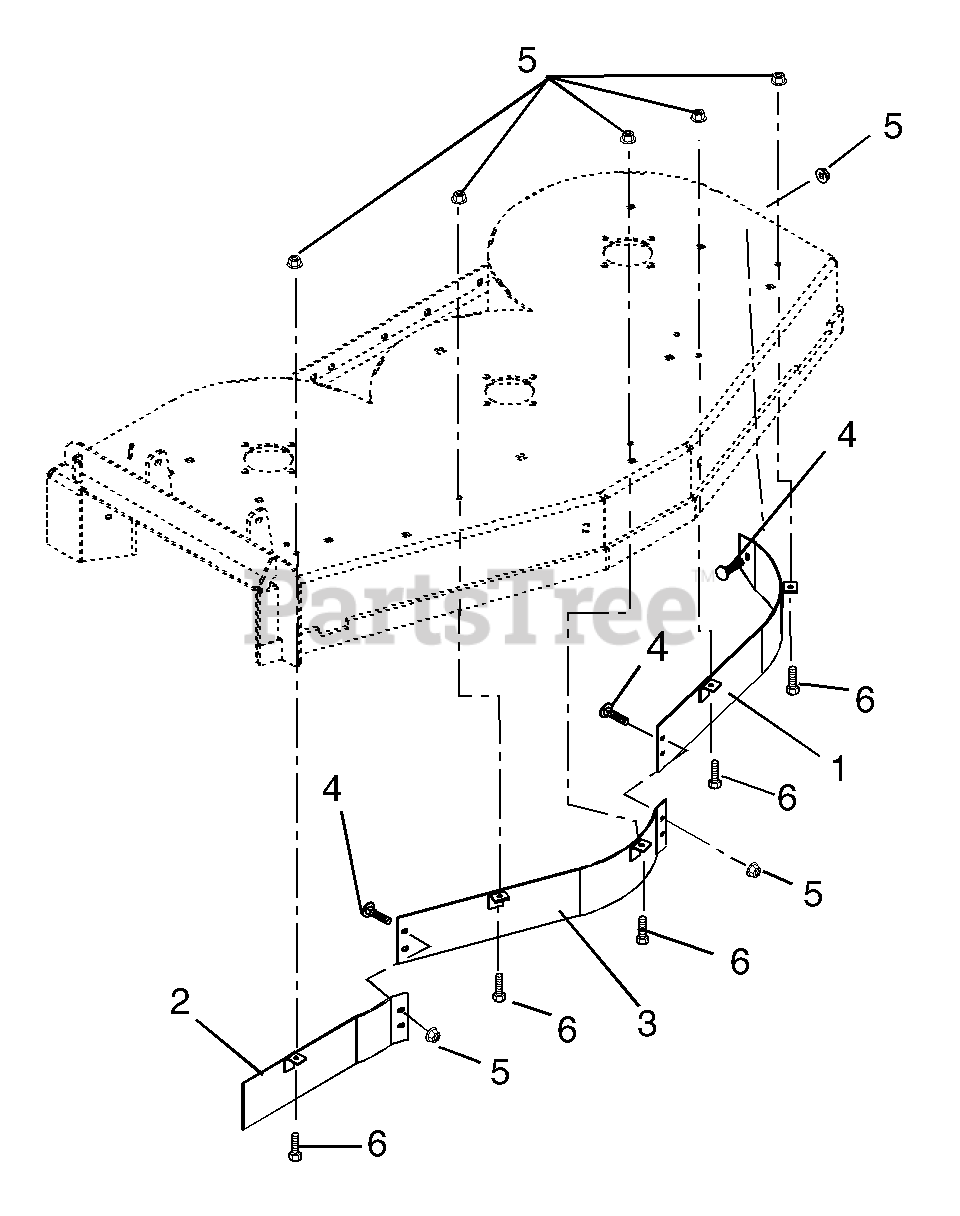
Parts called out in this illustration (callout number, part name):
1	Left Bahia Baffle-52"
2	Right Bahia Baffle-52"
3	Center Bahia Baffle-52"
4	Round Head Square Neck Bolt, 5/16-18 x 3/4
5	Top-Locking Flange Nut, 5/16-18
6	Hex Bolt, 5/16-18 x 3/4
